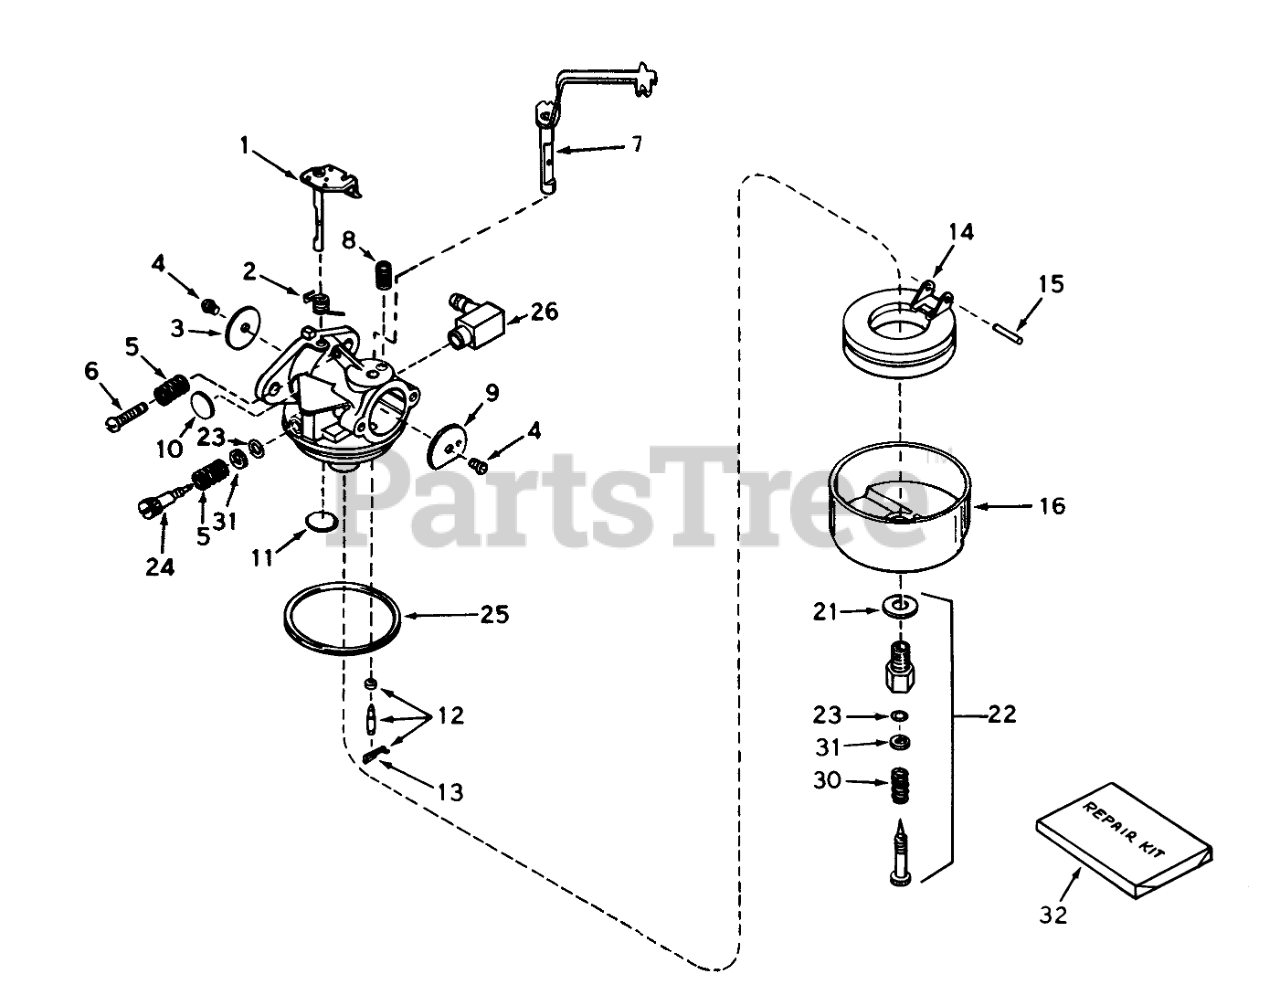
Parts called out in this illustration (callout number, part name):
1	Throttle Shaft and Lever ASM
2	Spring, Throtte Return
3	Shutter-Throttle
4	Screw-Shutter
5	Spring-Tension
6	Screw-Throttle Crack Screw / Idle Speed
7	Shaft & Lever Assy., Choke
8	Spring-Positioning, Choke
9	Shutter-Choke
10	Plug-Welch, Idle Mixture Well
11	Plug-Welch, Atmospheric Vent
12	Inlet Needle, Seat & Clip Assy. (Incl. No. 13)
13	Clip-Spring
14	Float,Carburetor
15	Shaft-Float
16	Bowl-Float (no drain)
21	Washer-Bowl Nut
22	Adjustment Screw Assy., Main (Incl. Nos. 21, 23, 30 & 31)
23	"O"Ring
24	Screw, Idle Adj.
25	O Ring-Bowl, Float
26	Fitting-Fuel
32	Kit-Repair
